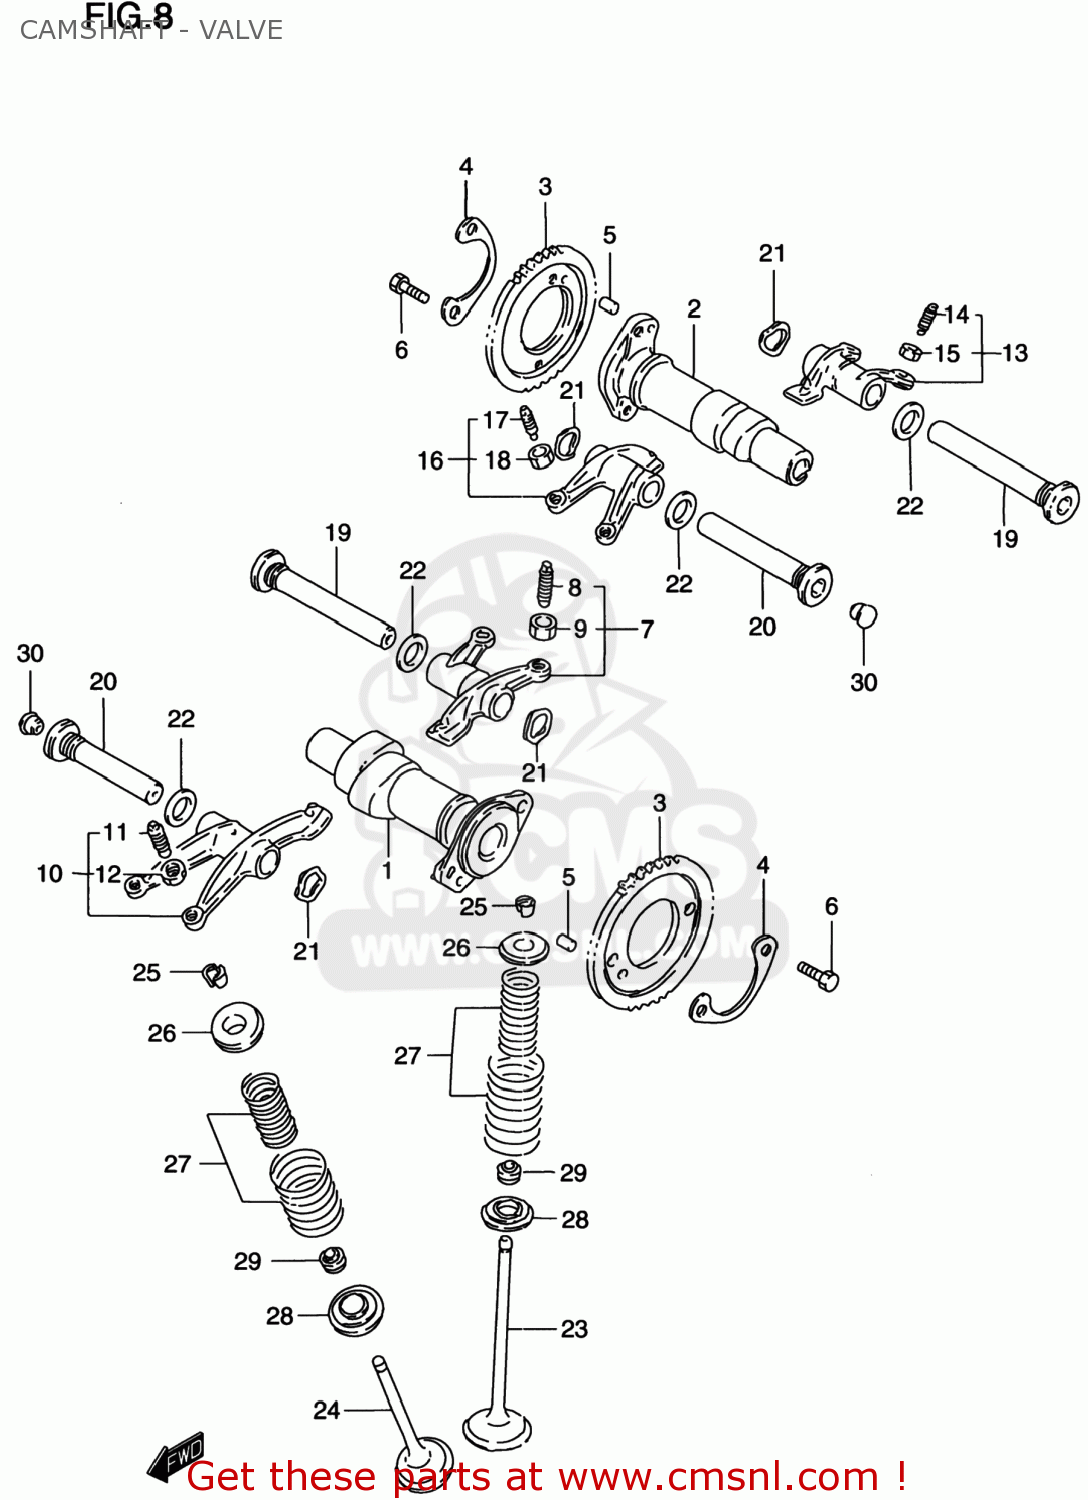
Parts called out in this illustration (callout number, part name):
1	CAMSHAFT,FR
2	CAMSHAFT,RR
3	SPROCKET,CAMSHAFT(NT:42)
4	WASHER,CAM CHAIN SPROCKET
5	PIN
6	BOLT(6X12.5)
7	ARM,INTAKE VALVE ROCKER FR
8	SCREW,TAPPET ADJUSTING
9	NUT,ADJUSTING SCREW
10	ARM,EXHAUST VALVE ROCKER FR
11	SCREW,TAPPET ADJUSTING
12	NUT,ADJUSTING SCREW
13	ARM,INTAKE VALVE ROCKER RR
14	SCREW,TAPPET ADJUSTING
15	NUT,ADJUSTING SCREW
16	ARM,EXHAUST VALVE ROCKER RR
17	SCREW,TAPPET ADJUSTING
18	NUT,ADJUSTING SCREW
19	SHAFT,INTAKE VALVE ROCKER ARM
20	SHAFT,EXHAUST VALVE ROCKER ARM
21	WASHER
22	GASKET(13.8X18.8X4.8) (NAS)
23	VALVE,INTAKE
24	VALVE,EXHAUST
25	COTTER,VALVE
26	RETAINER,VALVE SPRING
27	SPRING SET,VALVE
28	SEAT,VALVE SPRING
29	SEAL,OIL(5.5X11X8.2)
30	CAP(OD:10)
